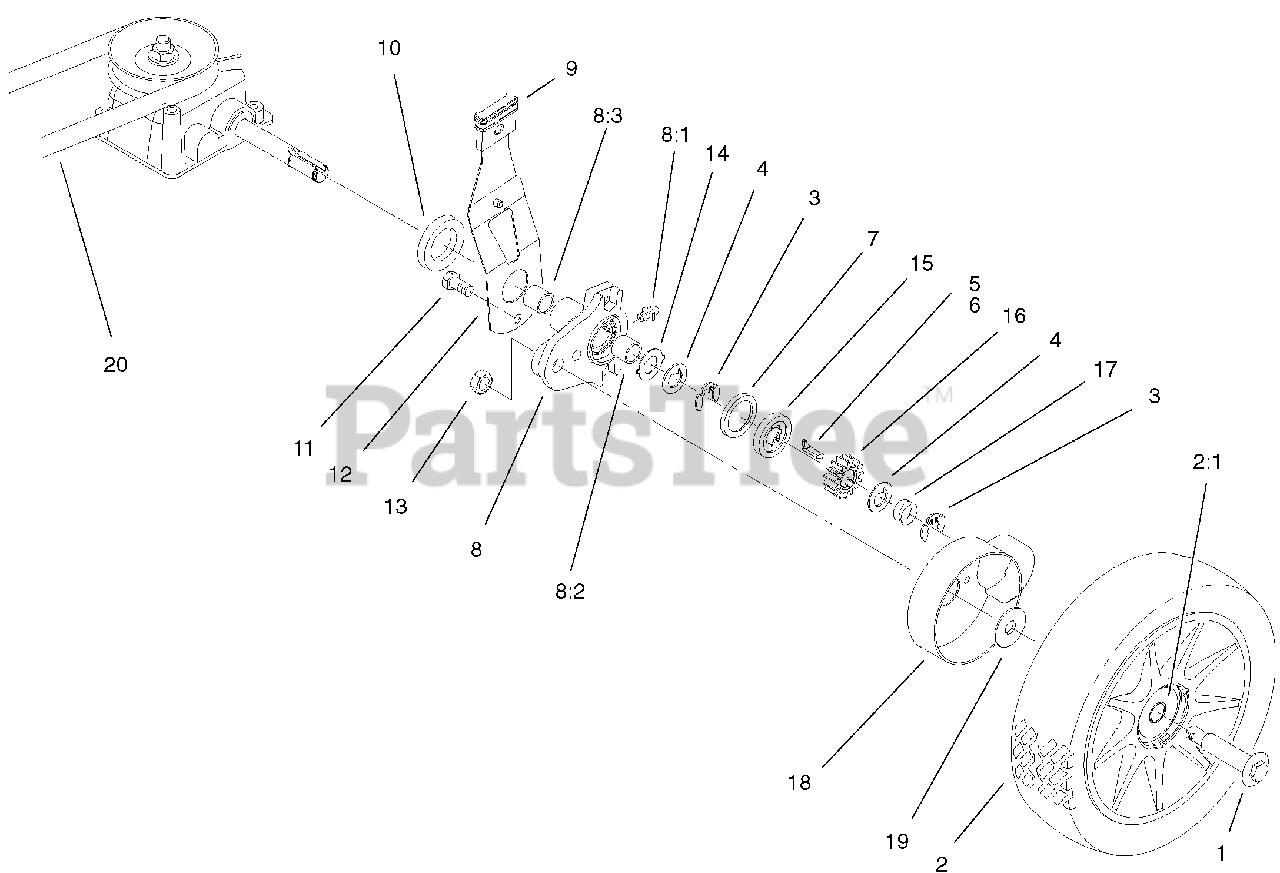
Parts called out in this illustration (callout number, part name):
1	Bolt-Shoulder
2	Wheel & Tire ASM
3	Ring-Klip
4	Washer-Thrust, Keyed
5	Key-Rocking, LH
7	Ring-Friction
8	Arm ASM-Rear Height Adjustment
8:1	Fitting-Zerk
9	Knob-Lever, Height Adjustment
10	Spacer-Axle Shaft
12	Rear Spring Arm ASM
14	Washer-Arm, Pivot
15	Washer-Clutch
16	Gear-Pinion
17	Spring-Compression
18	Cover-Wheel
19	Washer-Stepped
